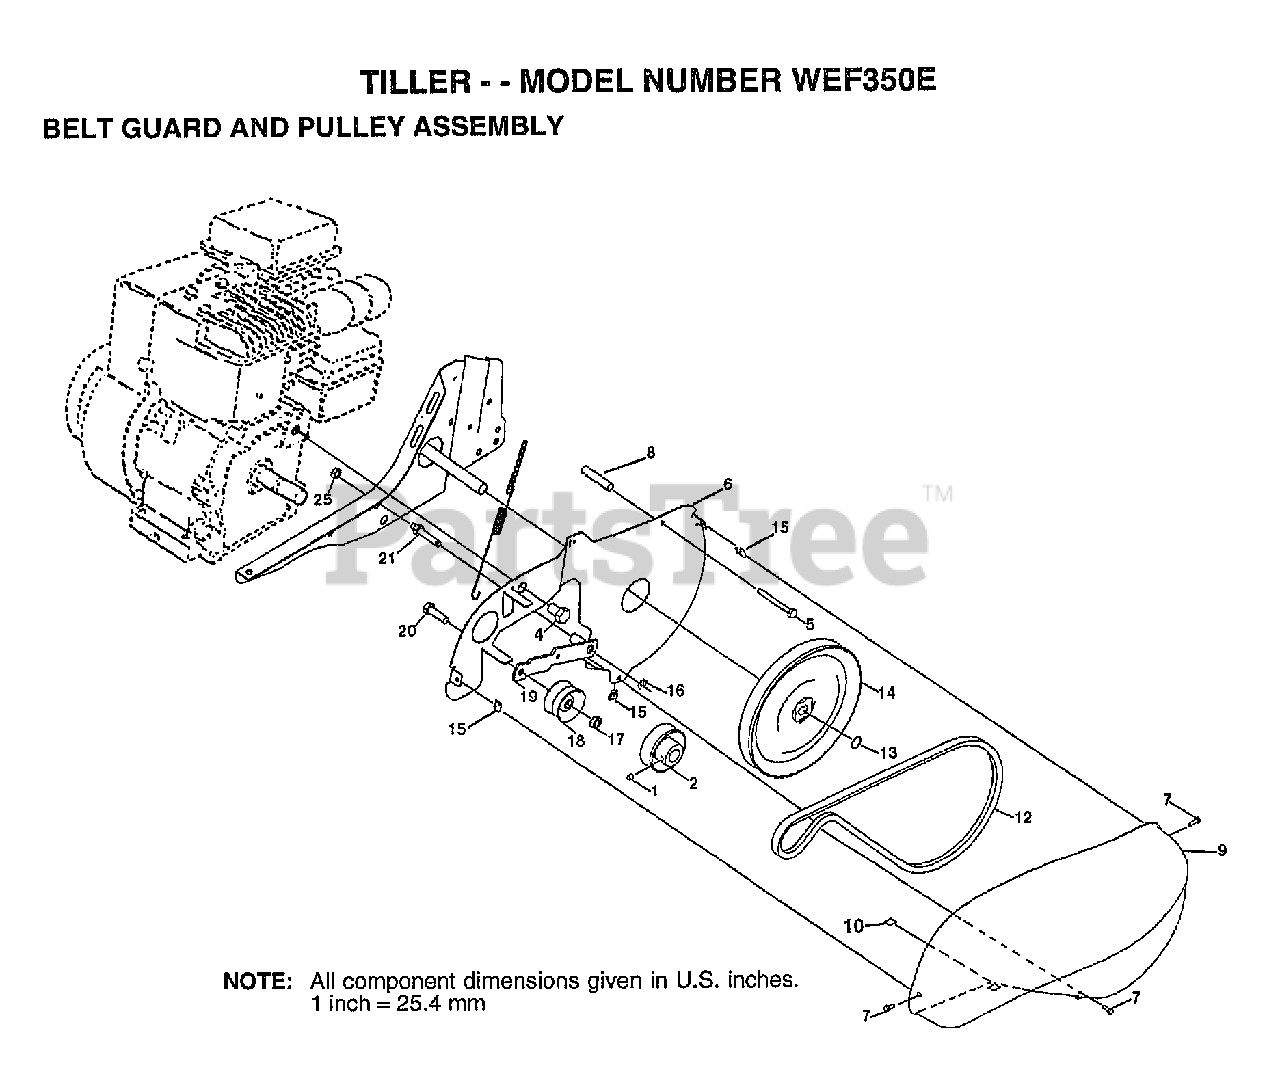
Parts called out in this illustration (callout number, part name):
1	SET SCREW
2	ENGINE PULLEY
4	BOLT.HEX.HEAD
5	BOLT.ROLLER.1/4-20X2 1/2
6	SHEILD.INNER.GUARD
7	SCREW HX WSH.HD#8-18X1/2
8	SPACER.SPLIT
9	GUARD
10	PAD IDLER TI
12	V BELT STD
14	SHEAVE.TRANS
15	NUT J CLIP #8
16	KLIP RING TI
17	NUT
18	"PULLEY,IDLER"
19	"ARM, IDLER"
21	SHAFT IDLER TI
25	JAM NUT TI
